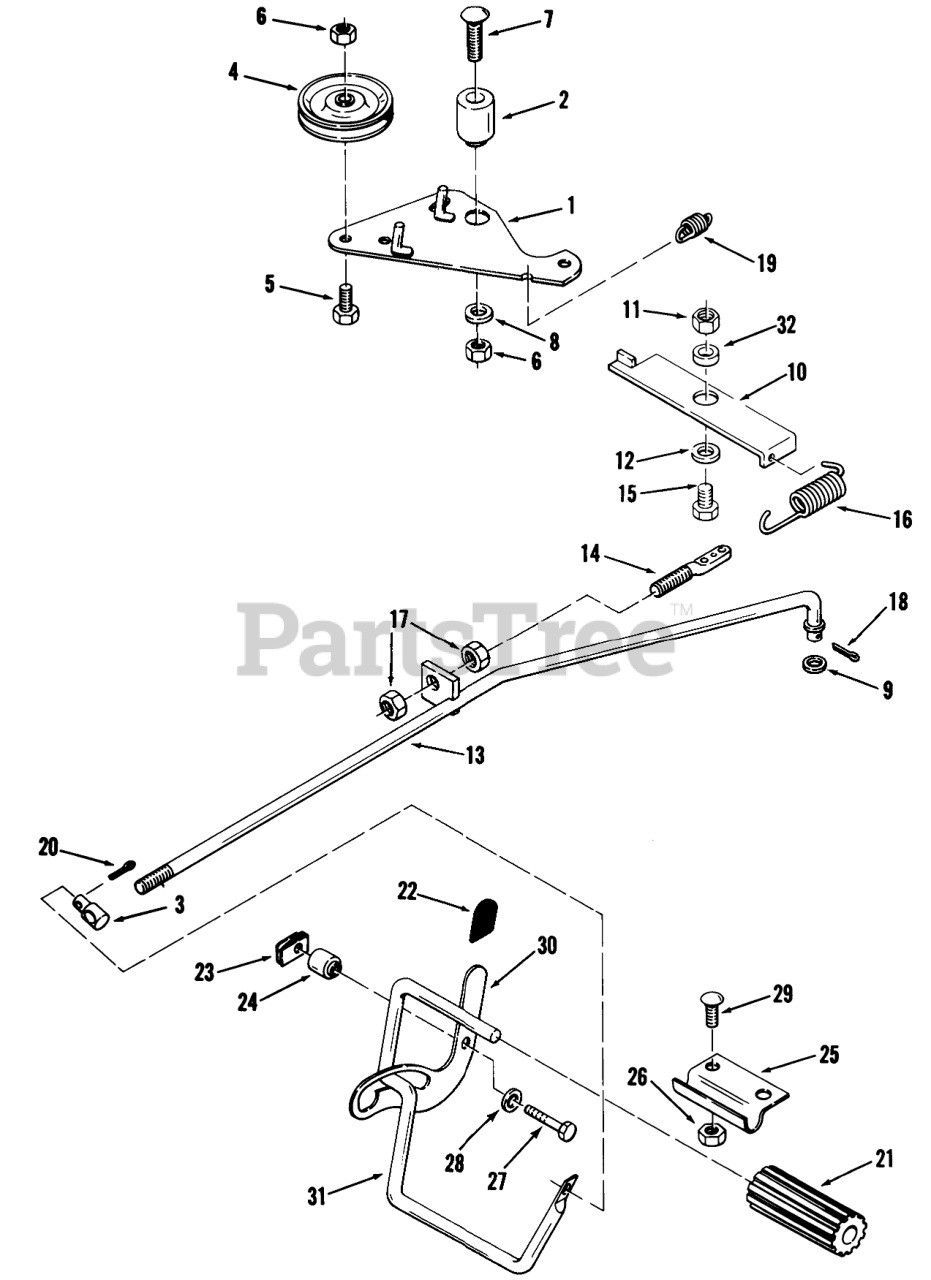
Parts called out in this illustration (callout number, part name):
3	TRUNNION
4	PULLEY-IDLER STATION
8	WASHER
12	WASHER 5/16 SAE
19	SPRING
22	GRIP
25	SPINDAL SUPPORT *R
